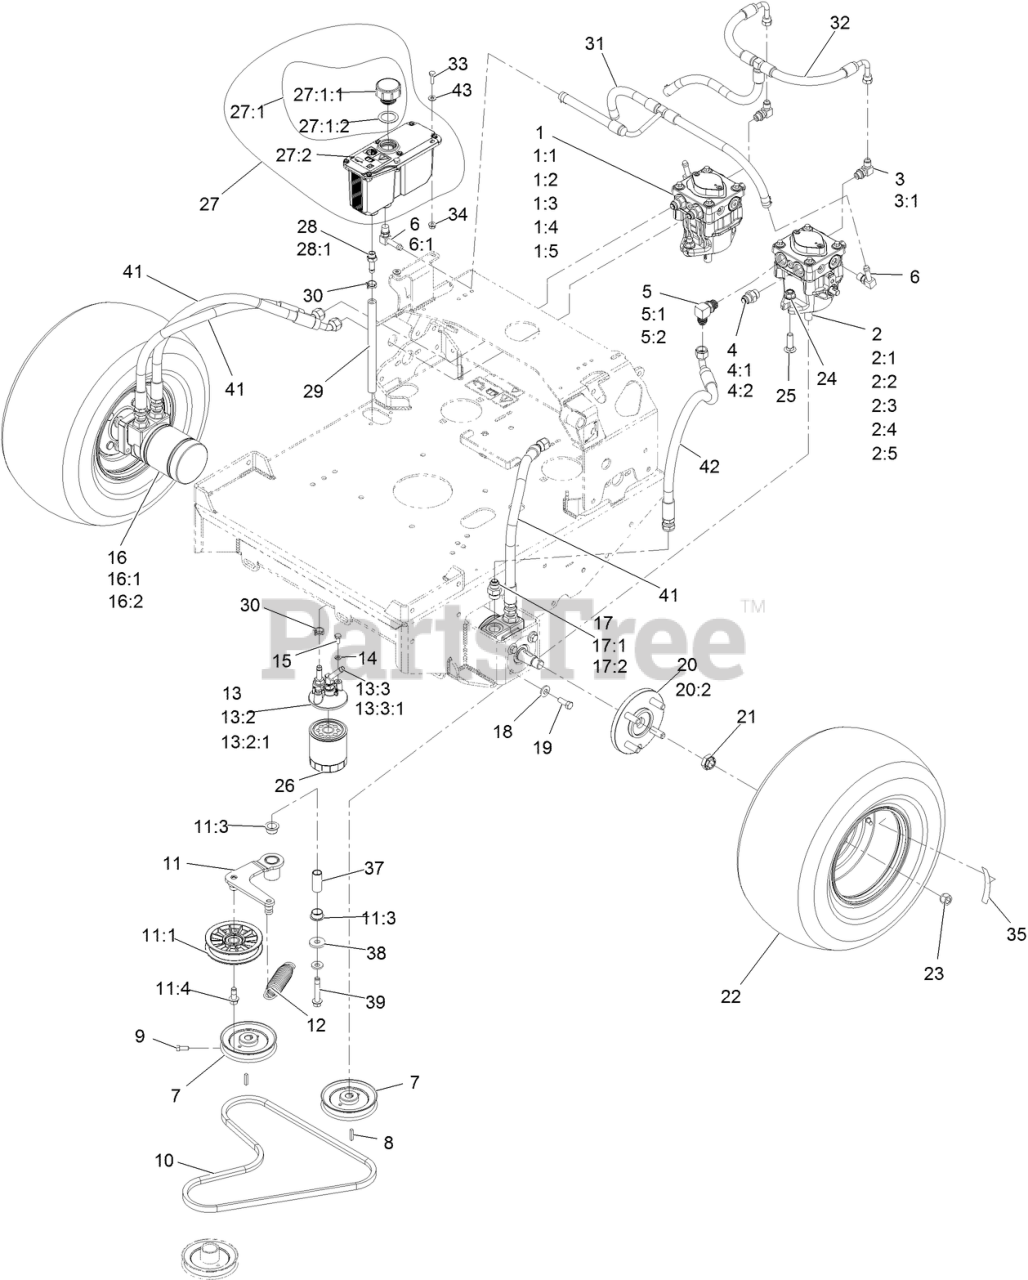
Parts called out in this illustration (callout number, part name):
1	PUMP-HYD PE RH TTH
1:1	INPUT SHAFT KIT
1:2	BEARING-THRUST
1:3	CYLINDER BLOCK KIT
1:4	SEAL OVERHAUL KIT
1:5	KIT, 10CC/12CC PUMP KIT
2	PUMP-HYD PE LH TTH
2:1	INPUT SHAFT KIT
2:2	BEARING-THRUST
2:3	CYLINDER BLOCK KIT
2:4	SEAL OVERHAUL KIT
2:5	KIT, 10CC/12CC PUMP KIT
3	FITTING-ELBOW, 90 DEG
3:1	O-RING
4	FITTING-STRAIGHT
5	FITTING-90 DEG
6	FITTING-ELBOW, 90
6:1	O-RING
7	SHEAVE ASM
9	SCREW-SET, SQH
10	BELT
11	ASM, PUMP IDLER
11:1	PULLEY-IDLER, FLAT
11:3	BUSHING-FLANGE
11:4	SCREW-HFH
12	SPRING-EXTENSION
13	ASM, FILTER HEAD
13:2	ADAPTER-STRAIGHT
13:2:1	O-RING
13:3	FITTING-BARBED, 45 DEG
13:3:1	O-RING
14	WASHER-LOCK
15	SCREW-HH
16	HYD MOTOR ASM
16:1	SEAL KIT
16:2	BEARING AND SEAL KIT
17	FITTING-STRAIGHT
17:1	O-RING
18	WASHER-BELLEVILLE
19	SCREW-HH
20	WHEEL HUB ASM
20:2	STUD-WHEEL
21	NUT-LOCK
22	ASM, DRIVE TIRE
23	NUT-LUG
24	NUT-HF, NI
25	BOLT-CARR
26	FILTER-25 MICRON, BI-DIRECTIONAL
27:1	Reservoir-HYD
27:1:1	Cap-Reservoir, HYD
27:1:2	GASKET-CAP
27:2	DECAL-WARNING
28	ADAPTER-STRAIGHT
28:1	O-RING
29	HOSE-CHARGE
30	CLAMP-HOSE
31	HOSE, CASE
32	HOSE, CHARGE
33	SCREW-HH
34	NUT-HHF
35	DECAL-TORQUE WHEEL LUG-HU
37	PIVOT, IDLER
39	SCREW-HHF
41	HOSE,HYDRAULIC W/COVER
42	HYD HOSE ASM
43	WASHER-FLAT
